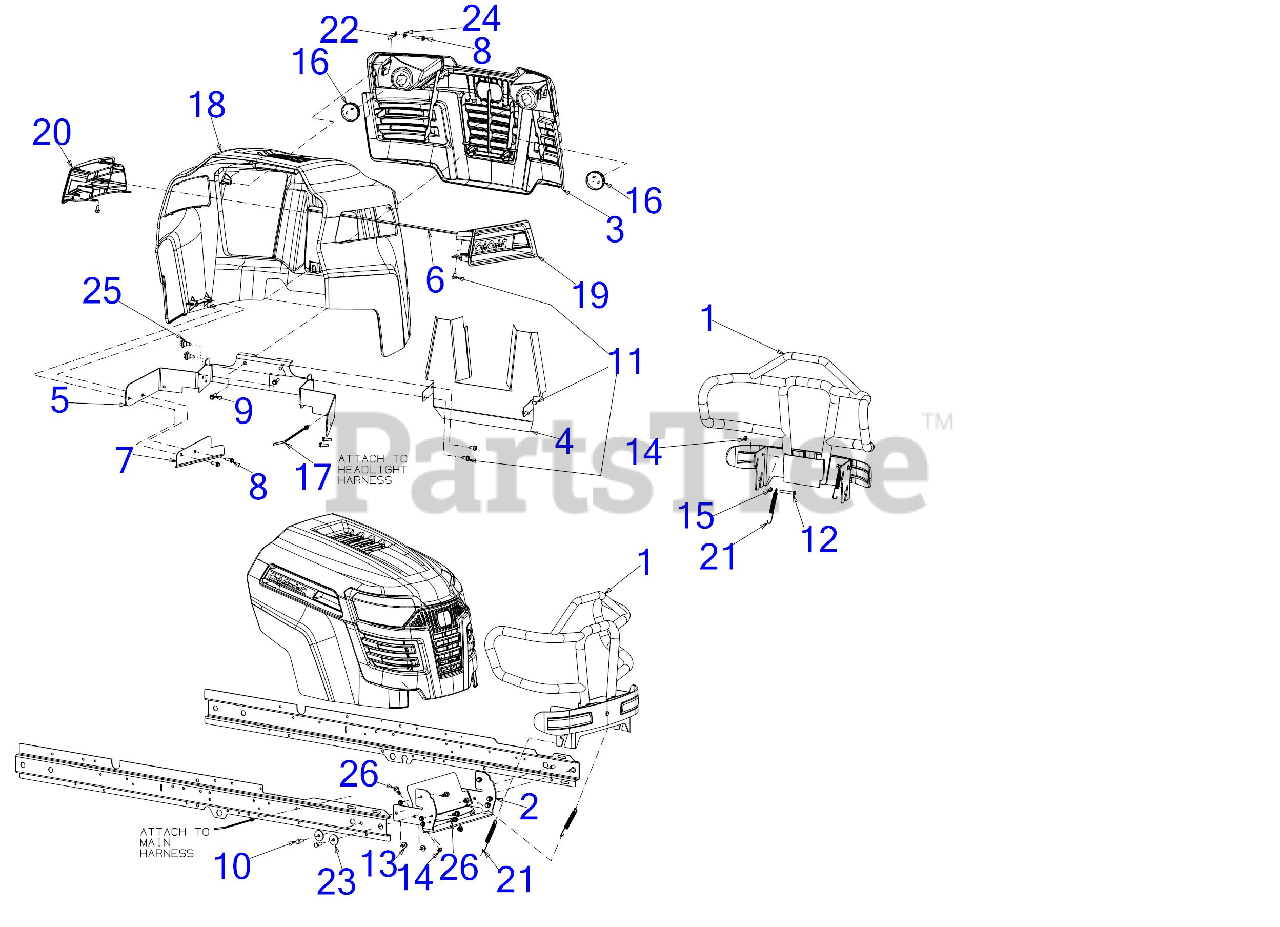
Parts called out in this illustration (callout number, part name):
3	GRILLE ASSEMBLY
4	DEFLECTOR SHIELD
5	HOOD PIVOT BRACKET
6	HOOD CROSS BRACE
7	HEAT EXHAUST SHIELD
8	SCREW 1/4 x .750
9	SCREW 5/16-14 x 1
10	SCREW 3/8-16 x 1 GR5
11	SCREW 1/4-20 X.500
12	SCREW 5/16-18 x 2.0 GR5
14	HEX FLANGE NUT
15	HEX NUT
16	HEADLIGHT ASSEMBLY
17	PUSH MOUNT TIE
18	HOOD (CUB YELLOW)
19	HOOD SCOOP (RH)
20	HOOD SCOOP (LH)
21	EXTENSION SPRING .54ODX5.0LG
22	LOCK WASHER 1/4
23	FLAT WASHER .390x1.500x.134
24	FLAT WASHER .271:.630:.065
25	SHOULDER SCREW .43X.29X5/16-18 TT
26	SHOULDER SCREW .43 X.35,5/16-18
